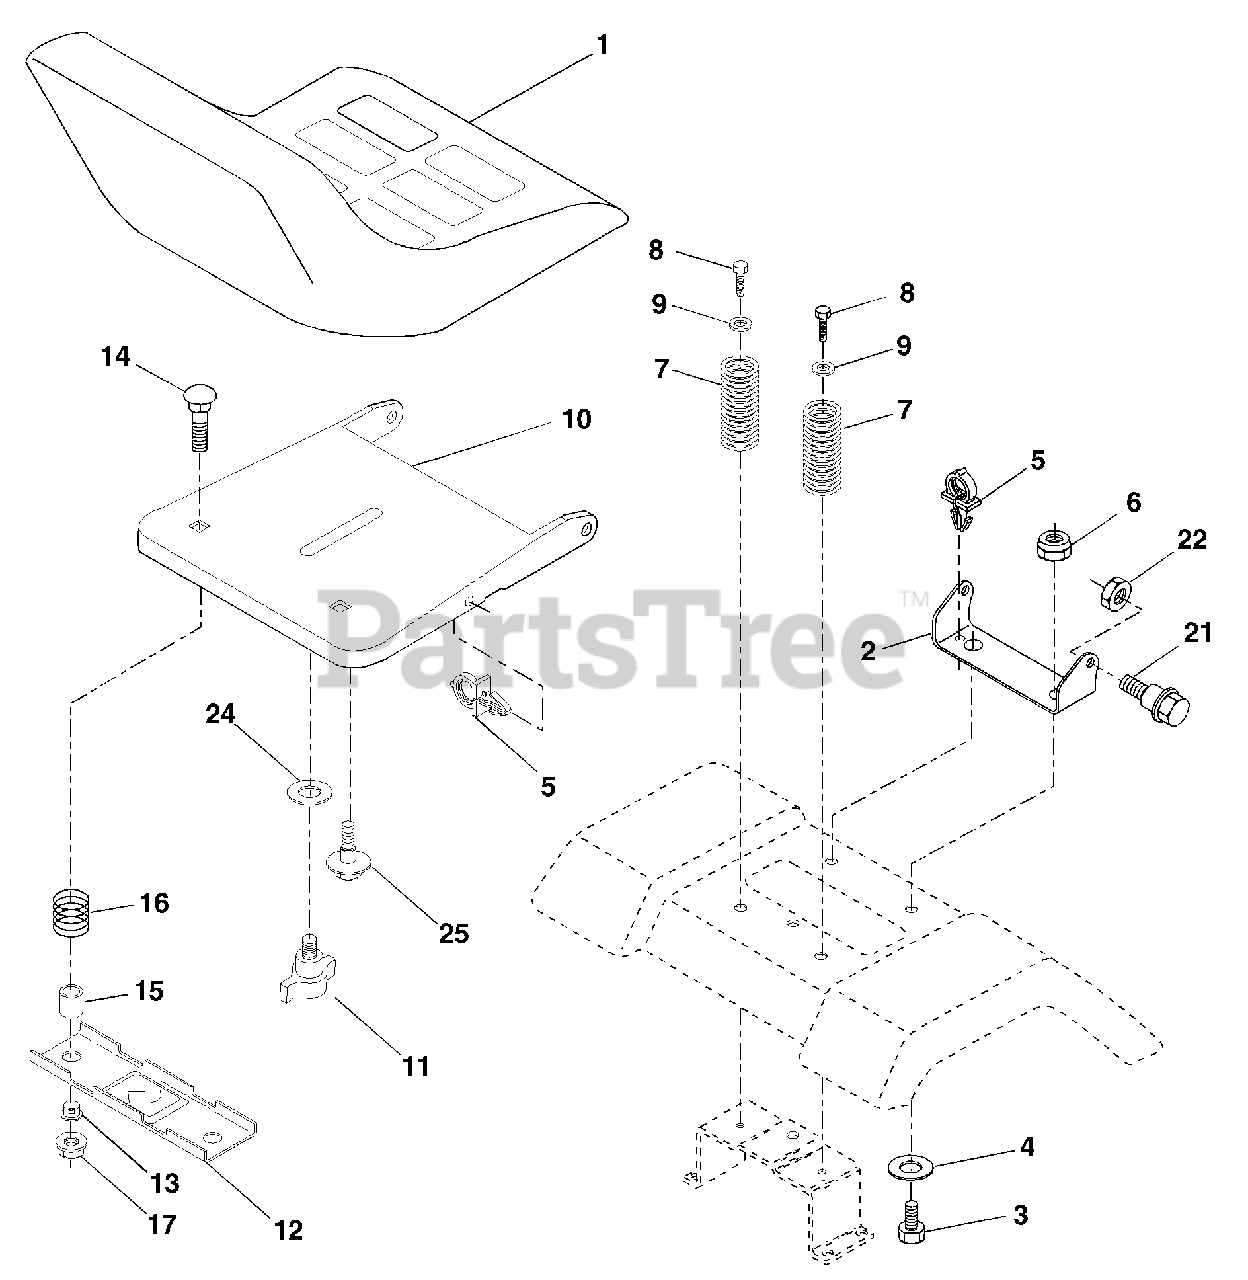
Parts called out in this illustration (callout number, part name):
1	Seat
2	Bracket Pivot Seat 8 720
3	Bolt Fin Hex 3/8-16unc X 1
4	Washer 13/32 X 1 X 10 Ga
5	Clip Push-In
6	Nut Hex w/Ins. 3/8-16 Unc
7	Spring Seat Cprsn 2 250 Blk Zi
8	Screw 3/8-16 x 1.5 Smgml
9	Washer 13/32 X 1 X 14 Ga.
10	Pan Seat
11	Knob Seat
12	Bracket Mounting Switch
13	Bushing Snap Blk Nyl 50 Id
14	Bolt Rdhd Sqnk 1/4-20 x 1-1/2
15	Spacer Split 28 x 88
16	Spring Cprsn
17	Nut Lock 1/4 Lge Flg Gr 5 Zinc
21	Bolt Shoulder 5/16-18 Unc
22	Nut Hex Lock W/Ins 5/16-18
24	Washer 17/32 X 1-3/16 X 12 Ga.
25	Bolt Shoulder 5/16-18 X 62
